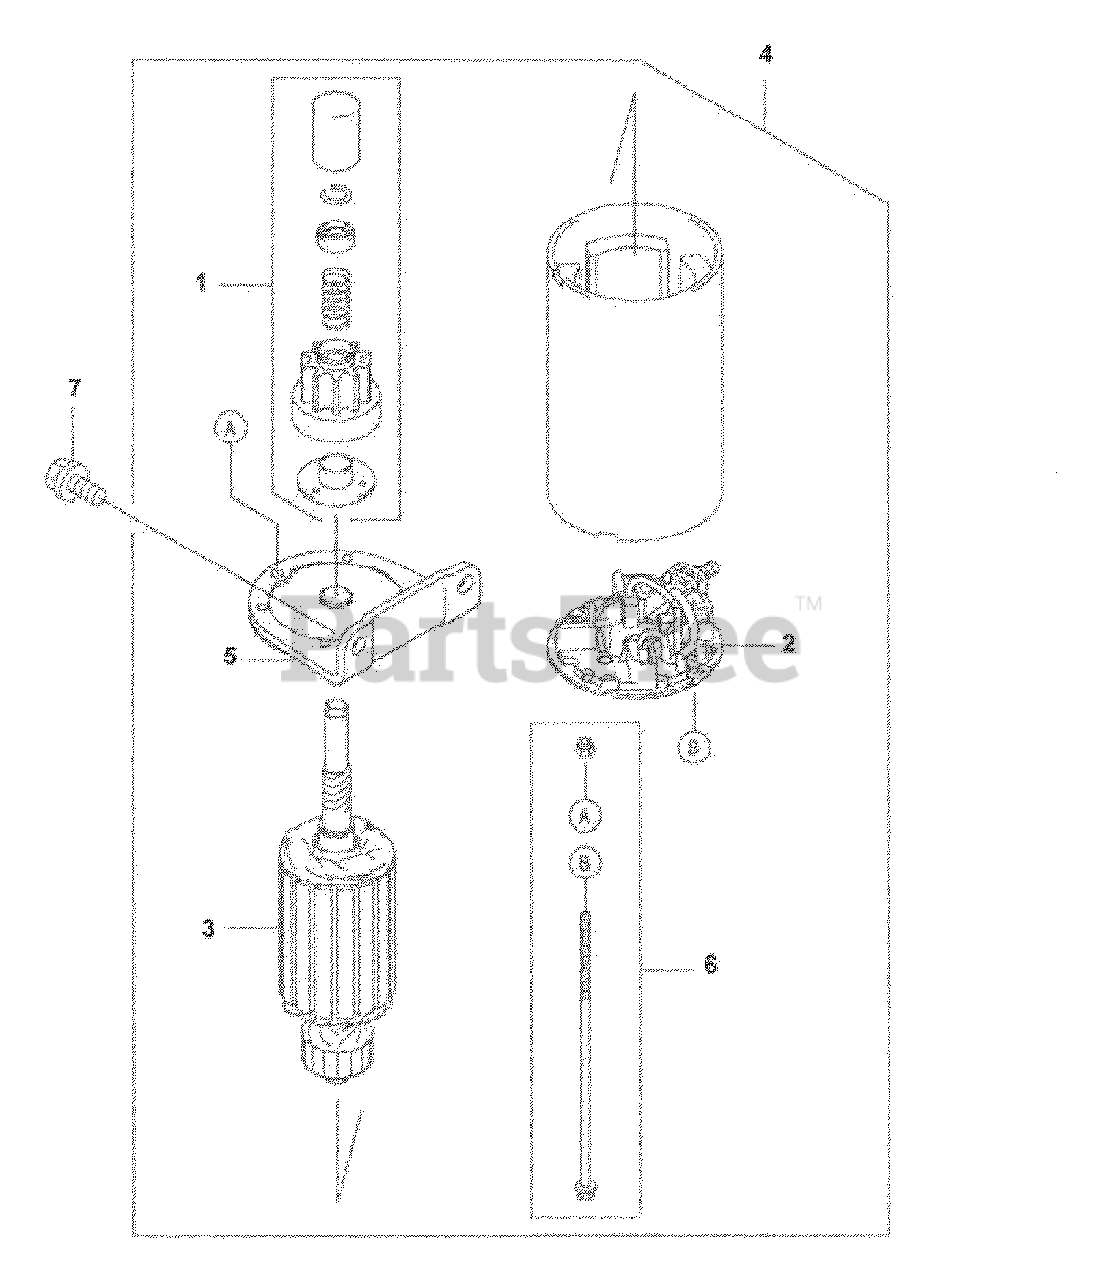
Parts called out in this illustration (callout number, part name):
1	Gear Assy.
2	Brush
4	Starter
5	Bracket Assy.
7	Flange Bolt
